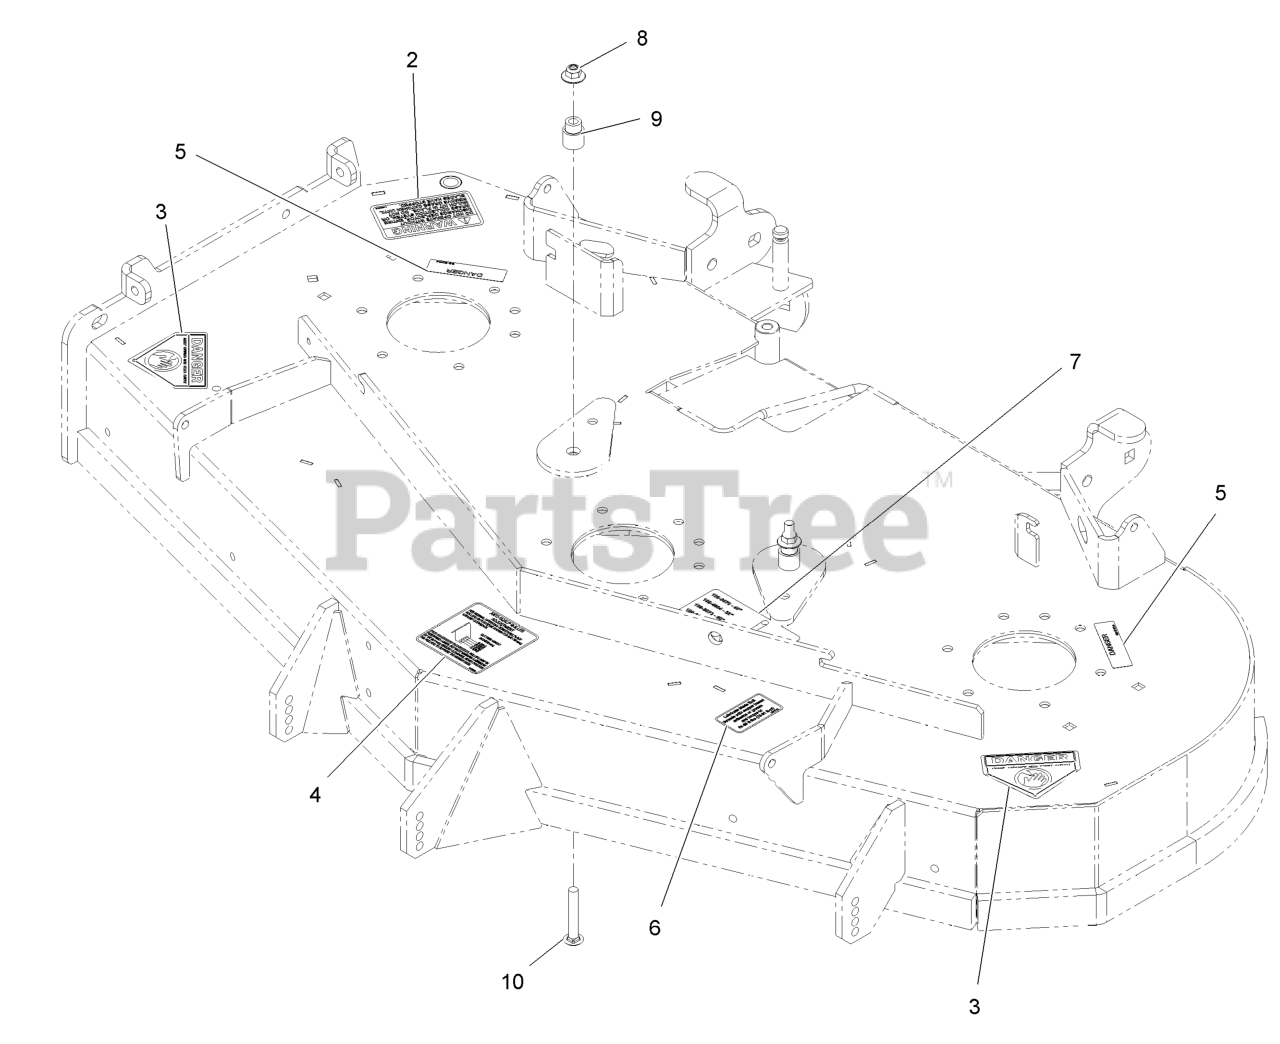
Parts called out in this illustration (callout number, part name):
2	DECAL-WARNING, DISCHARGE
3	DECAL-DANGER
4	DECAL,ANTISCALP
5	DECAL-COVER, MISSING
6	DECAL,BOLT TORQUE
7	DECAL,BELT ROUTING
8	Nut-Nyloc 3/8-16 Flg
9	BUSHING-IDLER
10	SCREW-CARR
